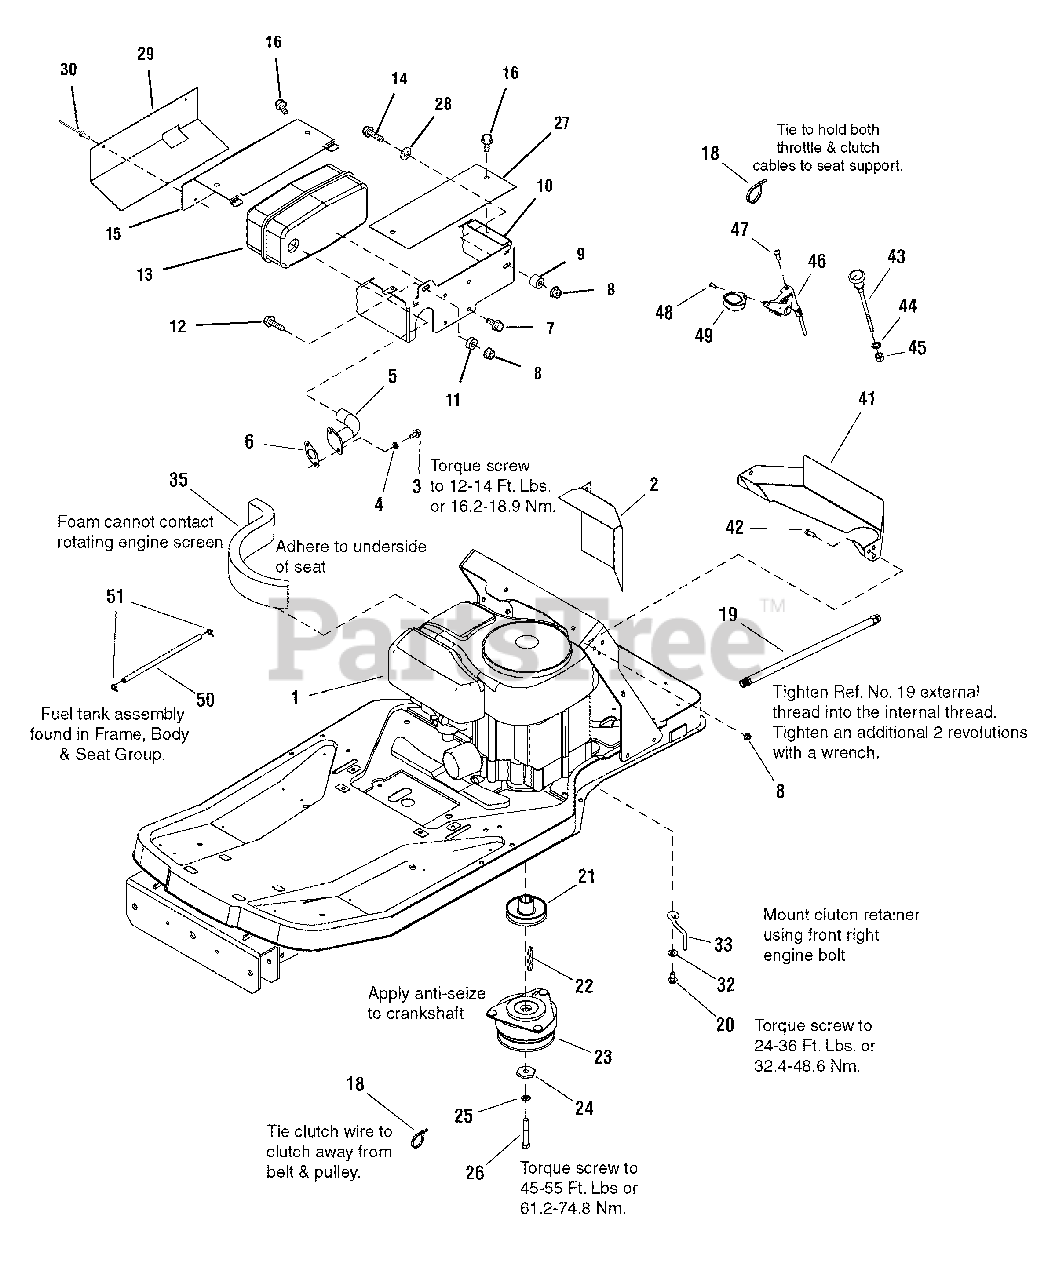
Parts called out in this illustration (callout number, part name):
1	*ENGINE, 20 HP Briggs & Stratton Intek
2	HEAT SHIELD, Inner
3	CAPSCREW, Hex Head, 5/16-18 x 3/4, G8
4	LOCKWASHER, Spring, 5/16
5	PIPE ASSEMBLY, Exhaust
6	GASKET, Exhaust
7	SCREW, Hex Whiz Lock Flange, 1/4-20 x 5/8
8	NUT, Hex Whiz Lock Flange, 5/16-18
10	BRACKET, Muffler/Heat Shield
11	SPACER, .390 ID x .9 OD x .34 LG, Powdered Metal
12	CAPSCREW, Hex Head, 5/16-18 x 1-1/4, G5
13	MUFFLER ASSEMBLY, Single
14	CAPSCREW, Hex Head, 5/16-18 x 1-1/2, G5
15	HEAT SHIELD, Outer Single
16	CAPSCREW, Thread Cutting, # 10 x 1/2
18	TIE, Self Locking, 3-5/8 LG
19	HOSE, Oil Drain, 16-1/2 LG
20	SCREW, Hex Washer Head Taptite, 3/8-16 x 1-1/4
21	PULLEY ASSEMBLY, Engine
22	KEY, Hi-Pro, 1/4 x 2-1/2
23	CLUTCH, Electric
24	WASHER, Hex, .453 ID x 1-1/2
25	LOCKWSHER, Spring, .438
26	CAPSCREW, Hex Head, 7/16-20 x 2-3/4, G5
27	HEAT SHIELD
28	WASHER, 5/16, .34 ID x 3/4 OD x .06 THK
29	HEAT SHIELD
32	WASHER, 3/8, .41 ID x .87 OD x .08 THK
33	RETAINER, Clutch
35	SEAL, Foam Air Duct, 1 x 2-1/2, 12" LG
41	AIR DUCT, Inlet
42	CAPSCREW, Hex Head, 5/16-18 x 3/4, G5
43	CABLE, Choke
44	WASHER, Lock Internal Tooth, 3/8
45	NUT, Hex, 3/8
46	CONTROL, Throttle
47	SCREW, Pan Head Taptite Torx, 1/4-20 x 5/8
48	SCREW, Pan Head Taptite Combo, 310-16 x 3/4
49	KNOB, Throttle
50	HOSE, Fuel, 19.5"
51	CLAMP, Hose
